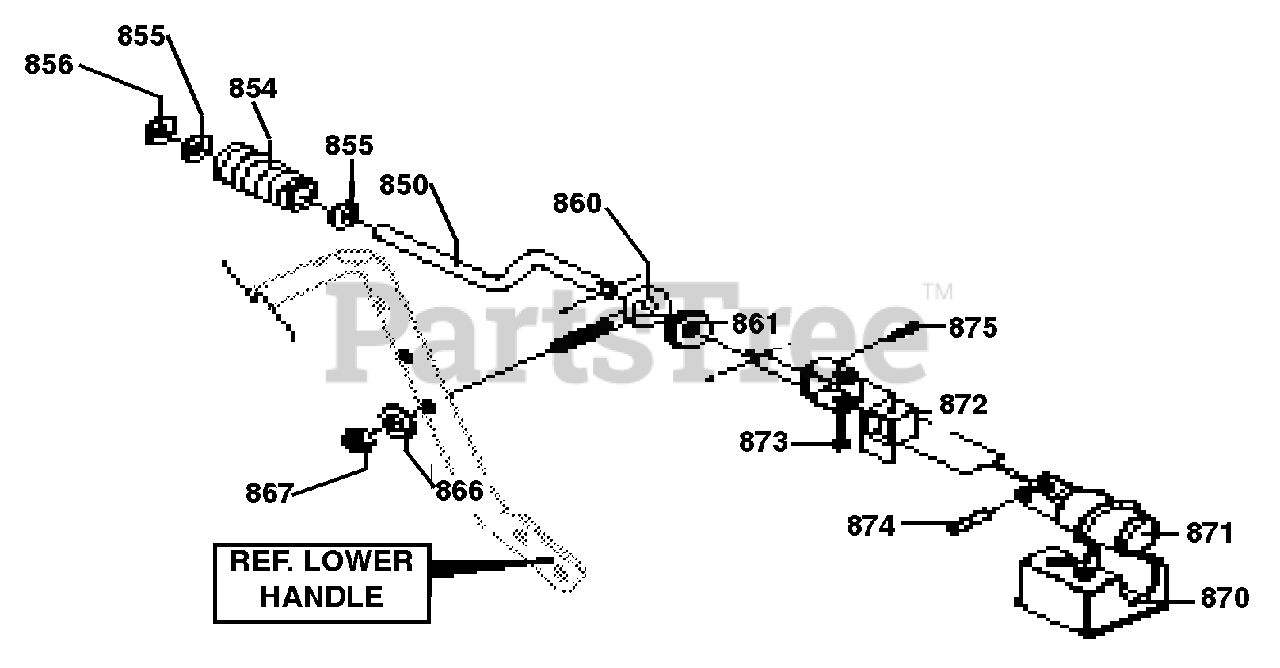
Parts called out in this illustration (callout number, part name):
850	Crank, Assy w/Yoke
854	Handle, Chute Crank
855	Flatwasher, .39 x .70 x .05
856	Ring, Ret E
861	Grommet, Eye Bolt
866	Flatwasher, .406 x .81 x .065
867	Nut, 3/8-16
870	Bracket, Worm
871	Worm, Gear Chute
872	Block, Univ Piv
873	Pin, Clevis
874	Pin, Univ Joint
875	Pin, Cotter
